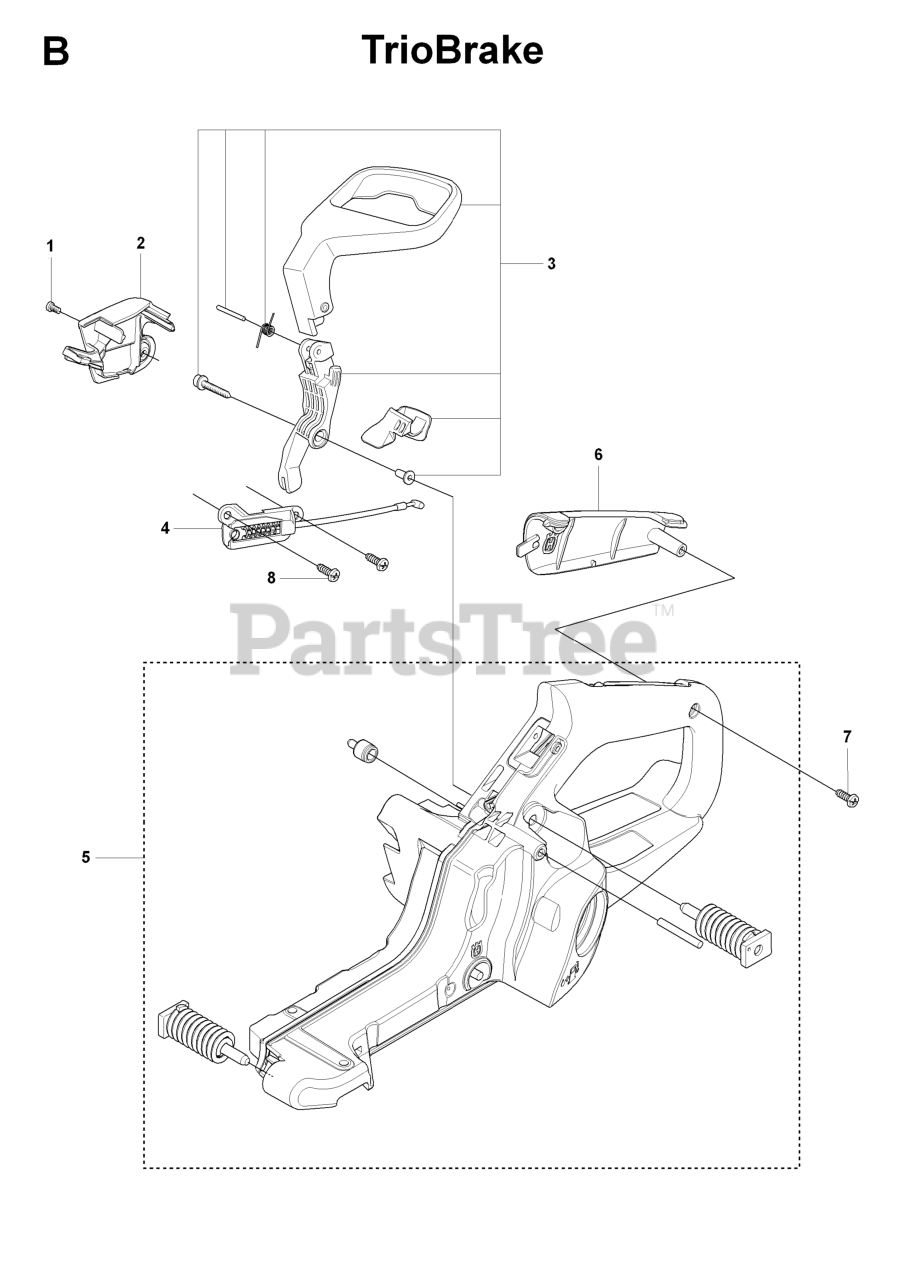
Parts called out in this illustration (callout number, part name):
3	HAND GUARD
5	FUEL TANK ASSY
6	HANDLE INSERT
